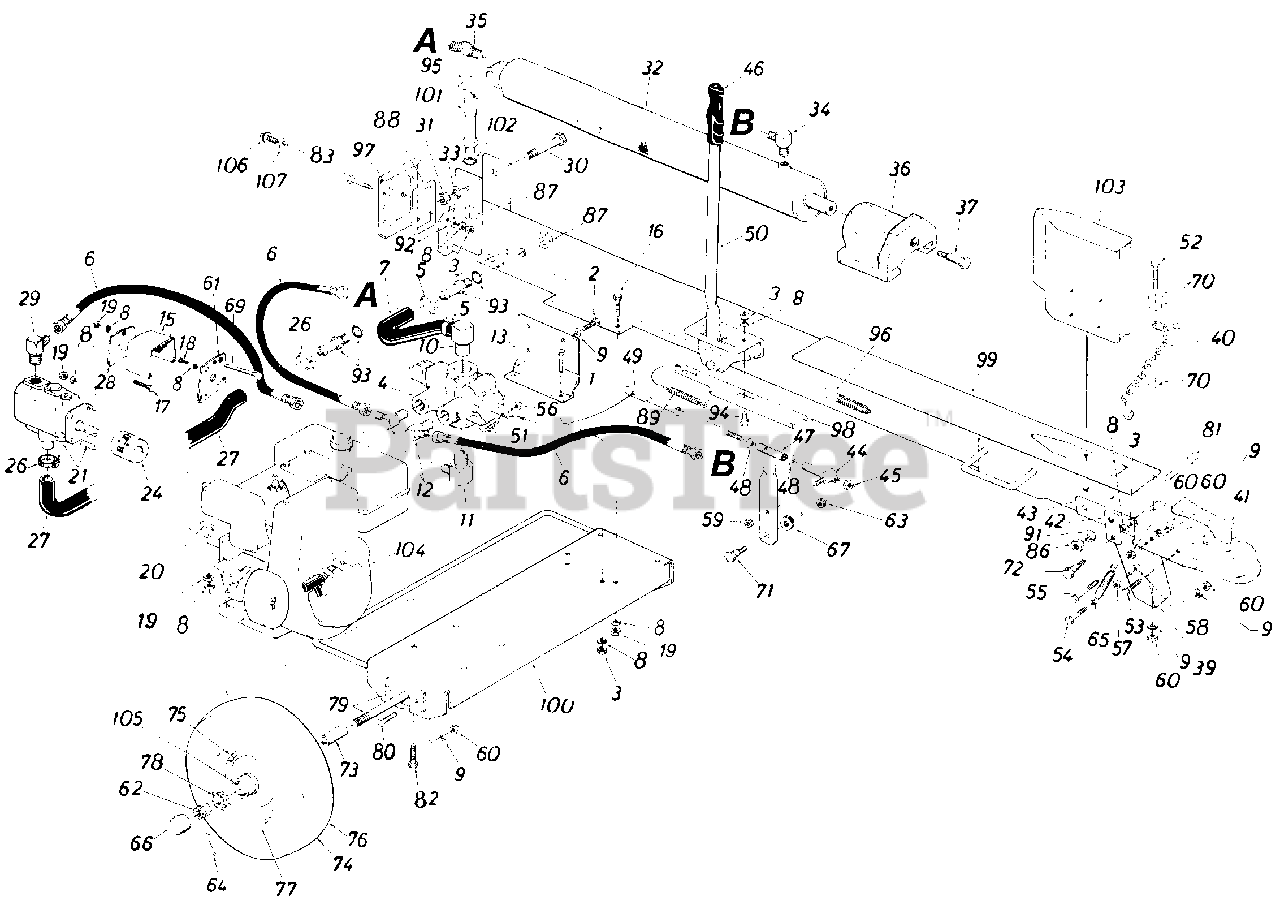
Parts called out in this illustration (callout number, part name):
1	Hex Bolt 5/16-18 x .75" Lg.
2	Hex Bolt 3/8-16 x .50" Lg.
3	Hex Nut 5/16-18 Thd.
4	Control Valve 400
5	Hose Clamp 5/8"
6	High Pressure Hose Ass'y. .38" I.D.
7	Return Hose Valve to Tank .34" I.D.
8	L. Wash. 5/16" I.D.
9	L.-Wash. 3/8" I.D.
10	Return Elbow
11	90ø Solid Male Adapter
12	90ø Solid Male Adapter
13	Valve Mtg. Plate
15	Coupling Shield
16	Hex Bolt 5/16-24 x 1.00" Lg.
17	Hex Bolt 5/16-24 x .75" Lg.
18	Hex Bolt 5/16-24 x .62" Lg.
19	Hex Nut 5/16-24 Thd.
20	Sq. Key 3/16" x 2.25" Lg.
21	Pump with Woodrull Key
24	Flexible Coupling Comp.
26	Hose Clamp 5/8"
27	Suction Hose 1.0" Dia.
29	90ø Solid Male Adapter
30	Hex Bolt 3/4" x 4.0" Lg.
31	Hex Nut 3/4" Thd.
32	Hydraulic Cylinder 3-1/2" Dia.
33	L.-Wash. 3/4" I.D.
34	High Pressure 90ø Elbow
35	45ø Male Adapter 3/4-16 MJ-3/8-18 NP
36	Pusher Plate
37	Shoulder Bolt. .62" Dia. x 4.75"Lg.
39	Flip Stand Bracket
40	Chain-Tow Hitch
41	Tow Hitch Ass'y. Comp.
42	Stand Pivot Bracket
43	Tow Hitch Brk't 2 x 3/16 10.25" Lg.
44	Ferrule Ass'y.
45	Hex Cent. L.-Nut 3/8-24 Thd.
46	Grip-Black Vinyl
47	Compression Spring
48	Special Washer .378 x 1.00" x .125 Thd.
49	Engagement Rod 3/8" Dia. x 9.0" Lg.
50	Engagement Handle
51	Hex Bolt 1/4-20 x 1.75" Lg.
52	Hex Bolt 3/8-24 x 1.25" Lg.
53	Hex Bolt 3/8-24 x .75"Lg.
54	Hex Bolt 1/4-28 x 1.00" Lg.
55	Hex Bolt 3/8-24 x 1.75" Lg. (Grade 5)
56	Hex Patch L.-Nut 1/4-20 Lg.
57	Hex Cent. L.-Nut 1/4-28 Thd.
58	Hex Nut 1/4-28 Thd.
59	Hex Cent. L.-Nut 5/16-18 Thd.
60	Hex Nut 3/8-24 Thd.
62	Hex Castle Nut 3/4-16 Thd.
63	Hex L.-Nut 3/8-16 Thd.
64	Cotter Pin 5/32" Dia. x 1.25" Lg.
65	Extension Spring .50" O.D. 3.97" Lg.
66	Hub Cap
67	Rubber Washer
69	Hex Bolt 5/16-24 x 4.0" Lg*
70	Fl.-Wash. .375" I.D. x .870" O.D. x .090
71	Shoulder Bolt .498" Dia. x .340" Lg.
72	Shoulder Bolt .437" Dia. x .268" Lg.
73	Spacer.75" I.D. x 1.12" O.D. x 1.56" Lg.
75	Air Valve-Tubeless
76	Tire Only 16.0 x 4.0 2 Ply
78	Roller Rearing 3/4" I.D.
79	Axle Ass'y. .75" Dia. x 35.25" Lg.
80	Hex Bolt 3/8-24 x 1.0" Lg.
81	Hex Bolt 5/8-18 x 3.50" Lg.
82	Hex Bolt 5/16-24 x 1.75 Lg.
83	Hex Bolt 5/16-18 x 1.50" Lg.
86	Hex Nut 5/1-18 Thd.
87	Hex Nut 11/16-12 Thd.
88	Gasket 2.62 x 5.12
89	Extension Spring .50" O.D. x 4.25" Lg.
91	L.-Wash. 5/8" I.D.
92	Fl.-Wash. .34" I.D. x .68" O.D. x .062 Thk.
93	Adapter 1.0" Tube 11/16-12 "O"-Ring
94	Shoulder Bolt .437" Dia. x .180" Lg.
95	Breather Cap
96	Strainer Tube Ass'y.
97	End Plate
98	Engagement Brk't. 1.39 x 11.75" Lg.
99	Complete Oil Tank Ass'y.
100	Engine Frame Ass'y.
101	Filler Tube Ass'y.
102	"O"-Ring 92" I.D. x 1.16" O.D. x .116 Dia.
103	Wedge Ass'y.
104	5 H.P. Engine
105	Bearing Seal
106	Hex Hd. Tap Scr. 5/16"
107	Gasket
